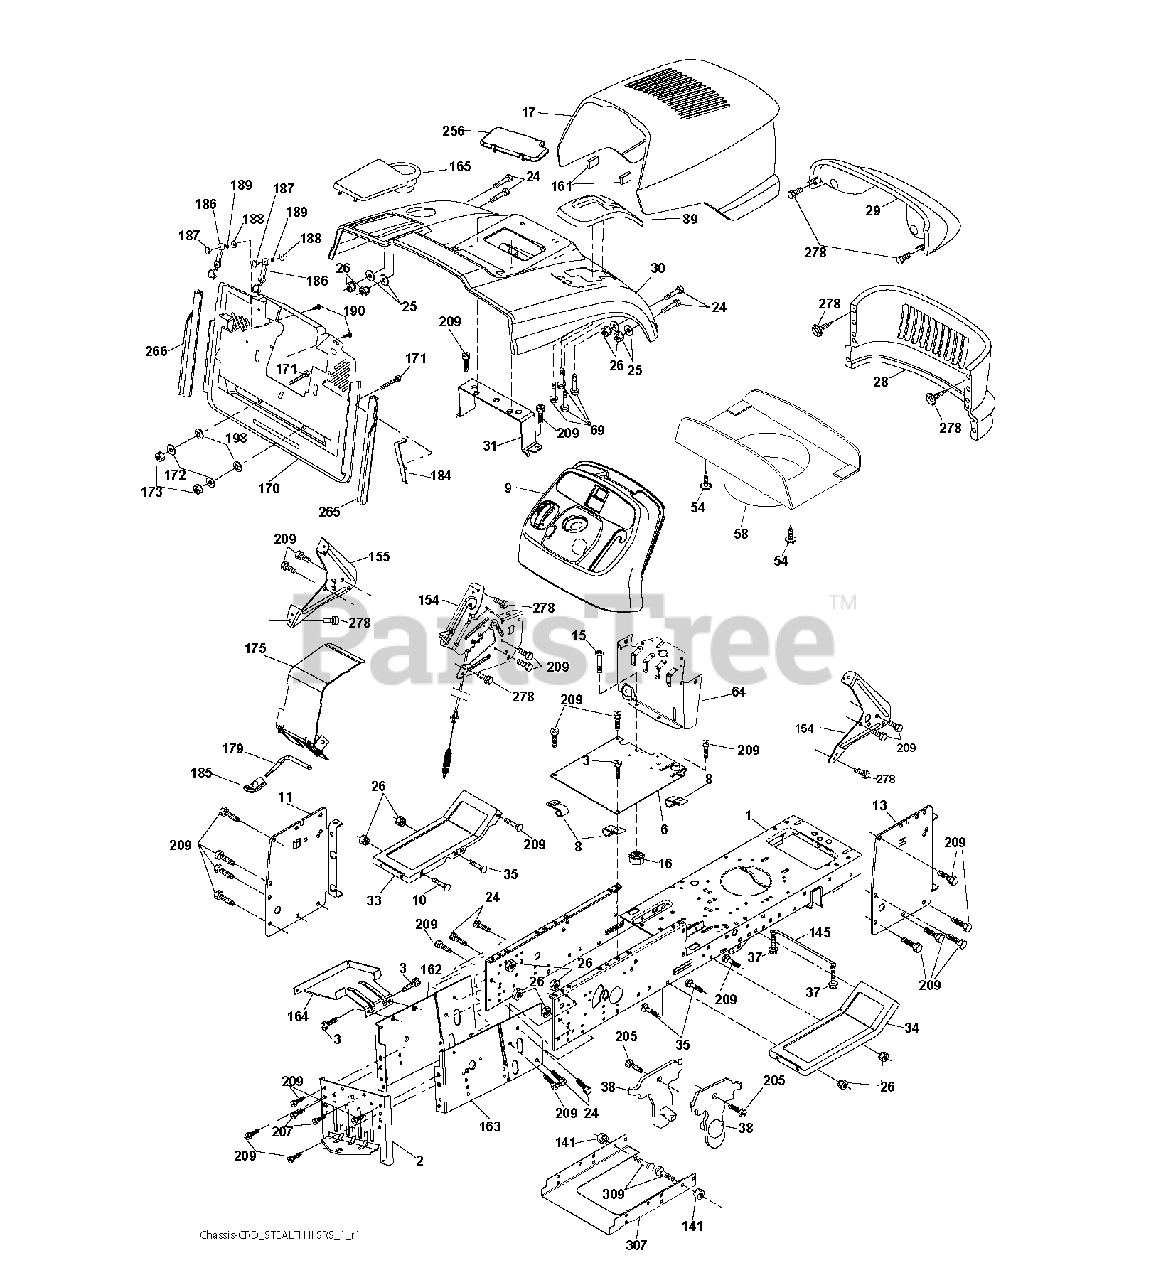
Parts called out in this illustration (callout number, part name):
1	CHASSIS
3	SCREW 3/8-16X3/4
8	CLIP,INSULATOR
10	BOLT D
13	PANEL DASH RH
16	NUT
25	WASHER
26	NUT
31	BRACKET SUPPORT FENDER
54	SCREW.WSHD.HEX10-32X5/8
58	DUCT HOOD
69	SCREW.HI-LO.CONSOLE
141	NUT LOCK FLG 3/8-16 UNC
145	ROD.PIVOT.HOOD
161	EXTRUSION BUMPER
164	SUPPORT
171	BOLT
172	WASHER
186	LATCH ASSY
187	WELDNUT
189	LOCKWASHER
207	SCREW, 5/16-18 X 1/2
209	SCREW, 3/8-16X3/4
278	SCREW.#10 X 0.750.BOS THREAD
